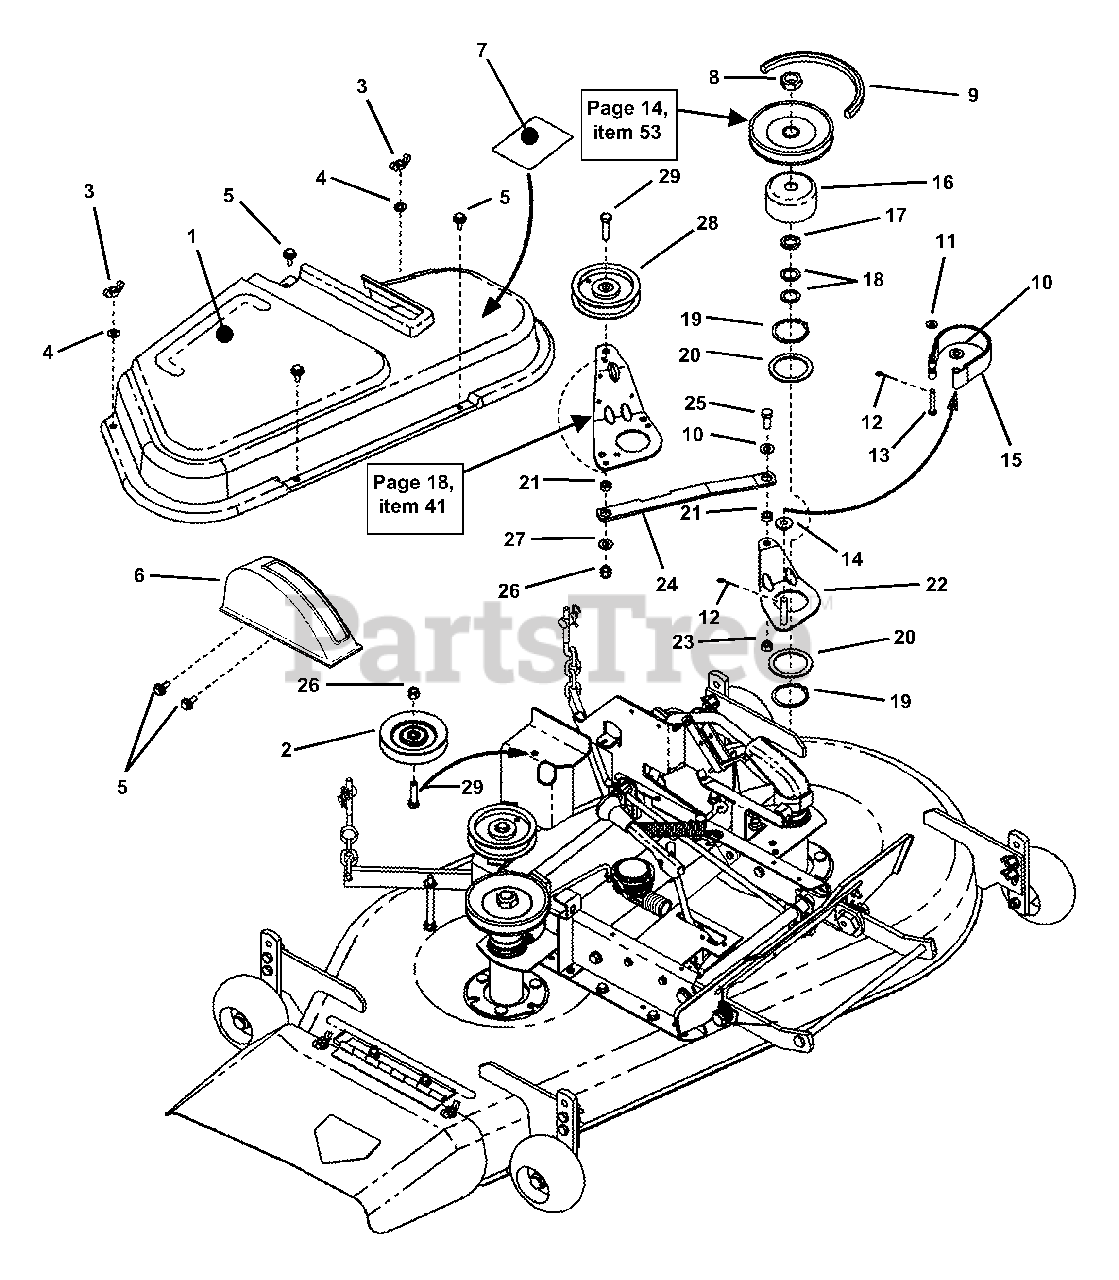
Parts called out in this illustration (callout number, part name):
1	COVER, Spindle 42"
2	PULLEY, Seam Welded Idler
3	WINGNUT, 5/16-18
4	WASHER, 11/32" x 11/16" x 1/16" Flat
5	SCREW, 1/4-20 x 5/8" Hex Washer Head, Self-Tap
6	COVER, Lift Quadrant
7	DECAL, Brake Operation
8	NUT, 3/4-16 Hex Jam Lock
9	BELT, (110.28", "5L" Section)
10	WASHER, 3/8" Flat
11	WASHER, 1/4 Flat
12	COTTER-PIN, 3/32 x 3/4"
13	PIN, 1/4 x 1-5/8" Clevis
14	SPACER
15	ASSEMBLY, Brake Band
16	DRUM, Brake
17	SPACER, 3/4" I.D.
18	WASHER, 3/4" Flat
19	RING, 2" External Retaining
20	WASHER, 2" I.D., Nylon
21	SPACER
22	WELDMENT, Brake Arm
23	NUT, 3/8-24 Hex Center Lock
25	SCREW, 3/8-24 x 1" Hex Head Cap Grade 5
26	NUT, 3/8-16 Hex Nyloc
27	WASHER, 3/8" Flat
28	PULLEY, 4-1/8" Flat Idler
29	SCREW, 3/8-16 x 1-1/2" Hex Head Cap Grade 5
